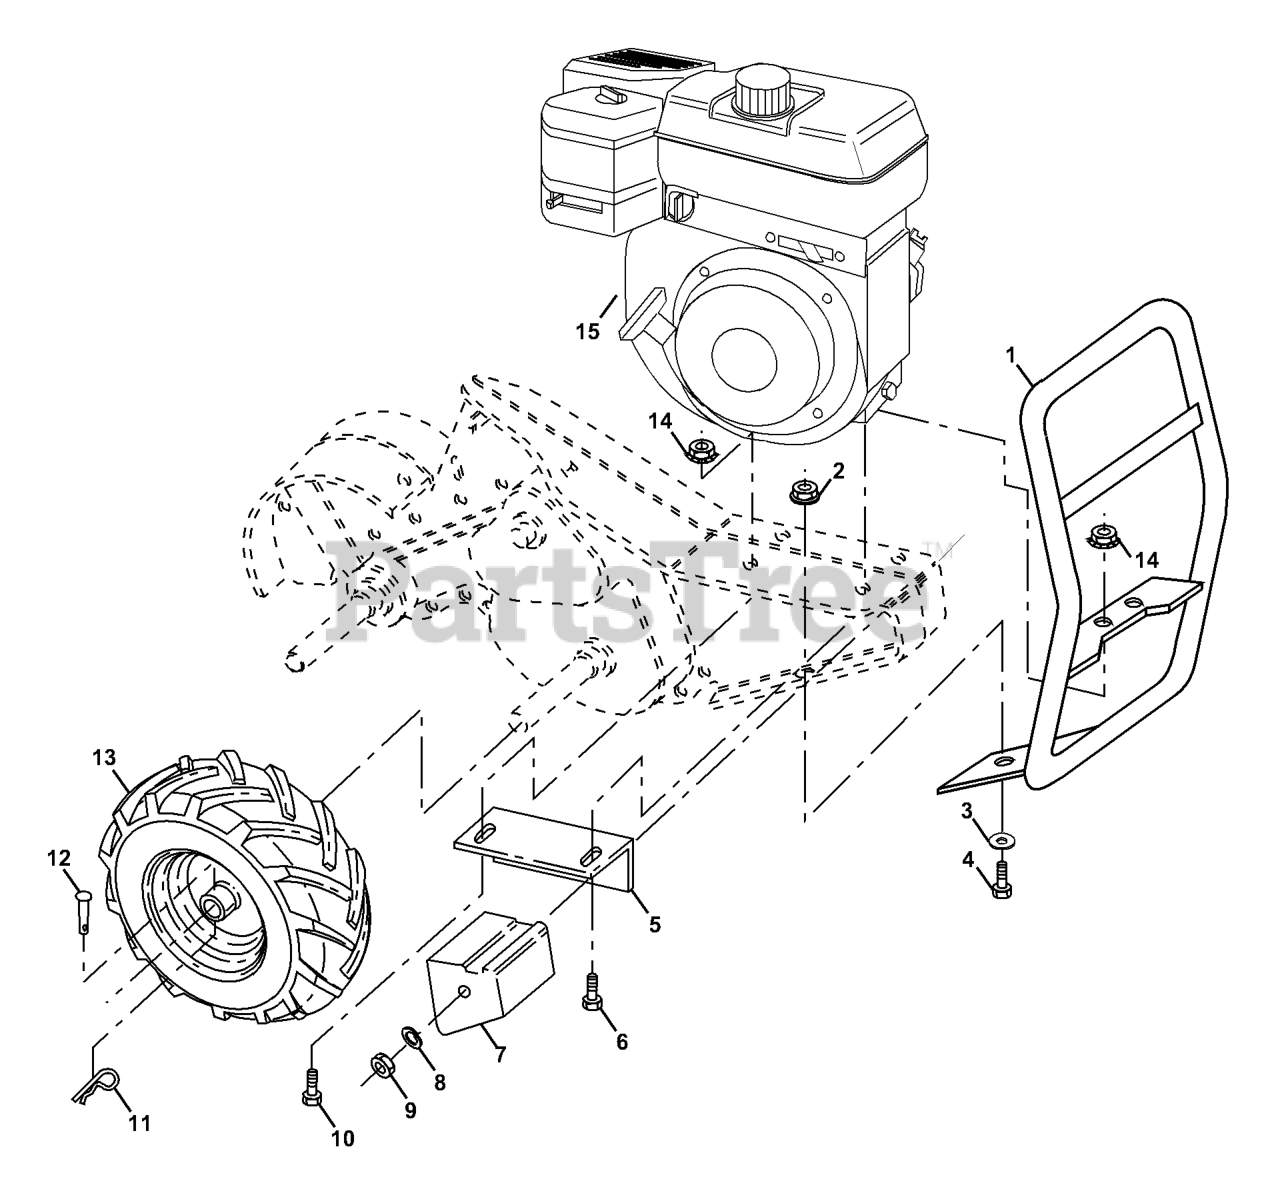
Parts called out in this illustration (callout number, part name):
1	BUMPER
2	LOCKNUT-FLANGE 5/16-18
3	WASHER
4	BOLT
5	DNO BRACKET RH CRT
6	Bolt, Hex 5/16-18 x 2
7	COUNTERWEIGHT, RH
8	WASHER, LOCK 3/8
9	NUT.HEX.3/8-16UNC
10	BOLT
11	RETAINER M
12	RIVET,DRILLED
13	TIRE.16X4-8.CHEVRON.TILLER
13	RIM
13	VALVE STEM LT
14	LOCKNUT-FLANGE 5/16-18
